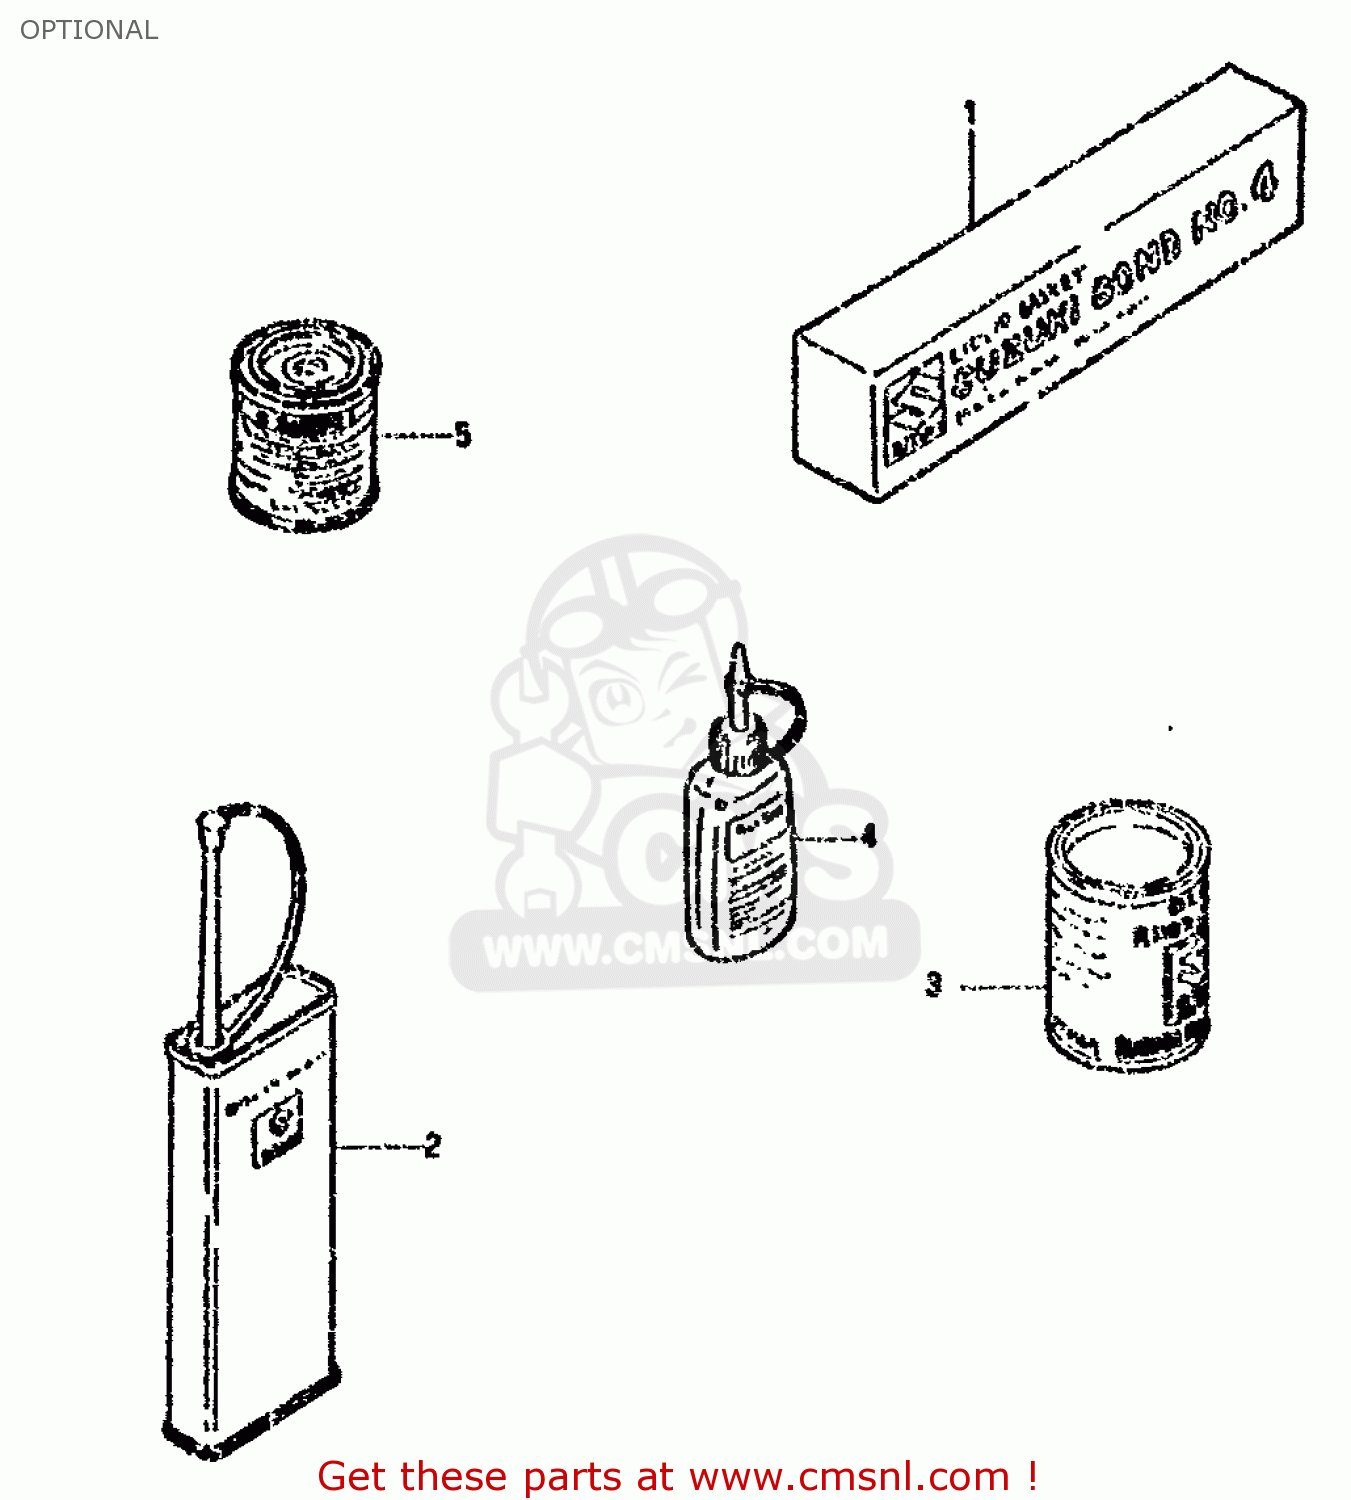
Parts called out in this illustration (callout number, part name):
1	BOND 1104
2	THREAD LOCK NO.1401 CLEAR 200G
3	GREASE(C)EP2 LITHIUM 150G
4	THREAD LOCK NO
5	PAINT,BLACK
